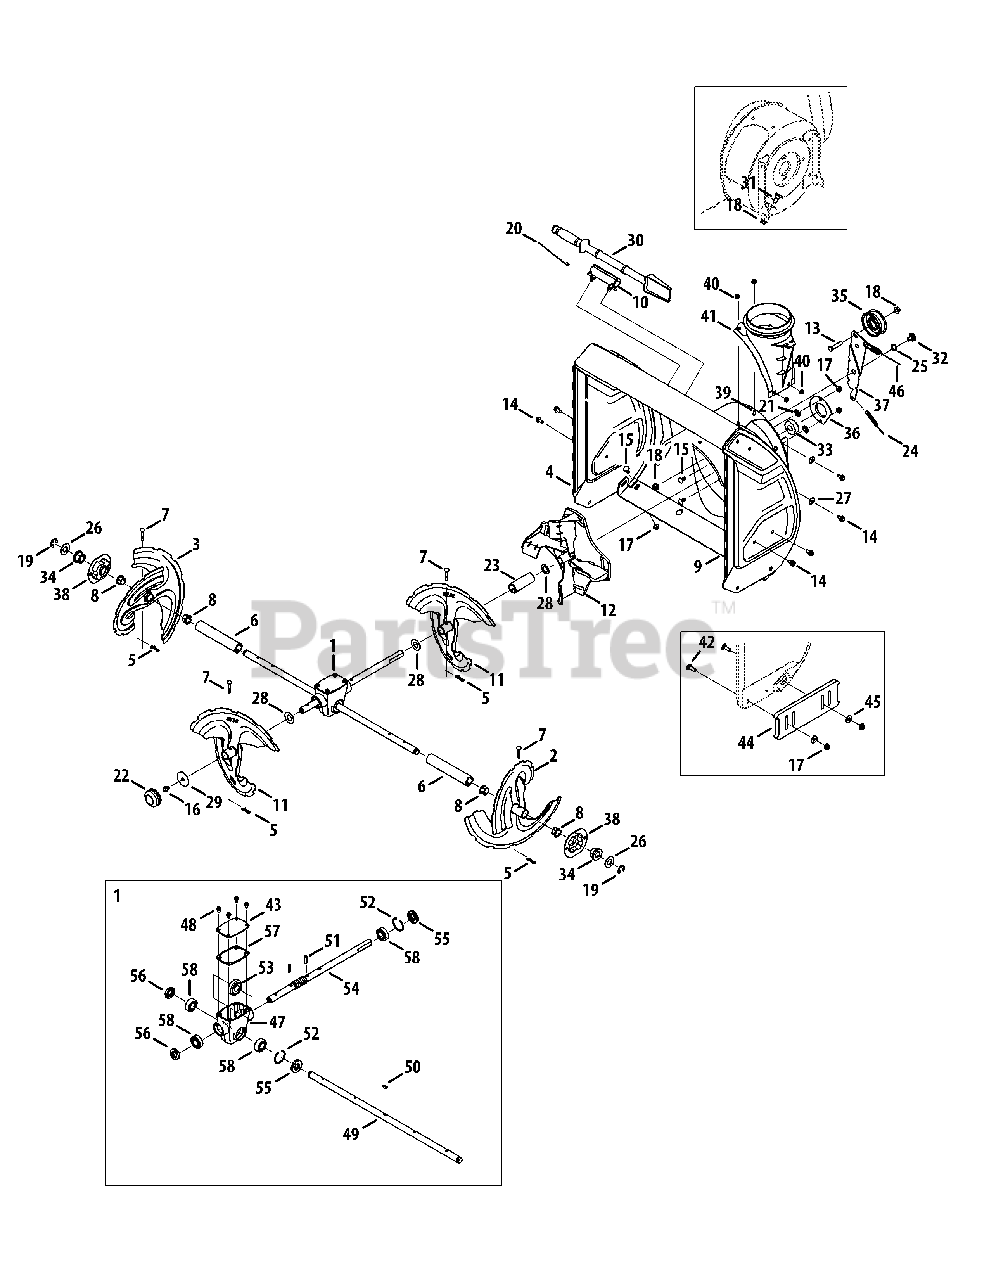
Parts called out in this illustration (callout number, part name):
1	Gearbox Assembly, Auger, 26"
2	Spiral Assembly - LH, 26" & 28"
3	Spiral Assembly - RH, 26" & 28"
4	Auger Housing, 26"
5	Bow Tie Cotter Pin
6	Spacer, 1.25 OD x .75 ID x 6.83 (26")
8	Flange Bushing, .800 x .910
9	Shave Plate, 26"
10	Clean-out Tool Mtg. Bracket
11	Accelerator Assembly
12	Impeller Assembly
13	Hex Bolt, 3/8-16 x 1.75
14	Screw, 5/16-18 x .750
15	Carriage Bolt, 5/16-18 x .750
16	Hex Washer Screw, 5/16-18 x .500
17	Flange Lock Nut, 5/16-18
18	Flange Lock Nut, 3/8-16
19	E-ring, .75
20	Cable Tie
21	Push-On Nut, .25 Dia.
23	Spacer, 1.35 OD x .76 ID x 2.755
24	Extension Spring, .38 OD x 4.59
25	Wave Washer, .625 x .885 x .0175
26	Flat Washer, .76 x 1.49 x .06
27	Bell Washer, .340 x .872 x .060
28	Flat Washer, .793 x 1.24 x .06
29	Flat Washer, .406 x 1.92 x .060
30	Clean-Out Tool
31	Shoulder Screw, 3/8-16 x .496 x .336
32	Shoulder Screw, 3/8-16 x .625 x .17
33	Flange Ball Bearing, .75 x 1.85
34	Hex Flange Bearing, .75 ID
35	Flat Idler Pulley
36	Bearing Housing
38	Bearing Housing
39	Carriage Screw, 1/4-20 x 0.75
40	Flange Lock Nut, 1/4-20
41	Chute Adapter
42	Spacer, Carriage, 5/16-18 x 1.00
43	Gearbox Cover
44	Deluxe Slide Shoe
45	Washer, Flat, .349 x .879 x .063
46	Auger Clutch Cable
47	Auger Housing
48	Screw, 1/4-20 x 0.75
49	Axle, Auger, 26"
50	Hi-Pro Key
51	Pin, Roll, .25 x 1.0
52	Retainer Ring
53	Worm Gear, 20T
54	Worm Shaft
55	Seal, .75 x 40mm x .25
56	Seal, .75 x 1.375 x .25
57	Gearbox Gasket
58	Ball Bearing, .75 x 40 x 12
